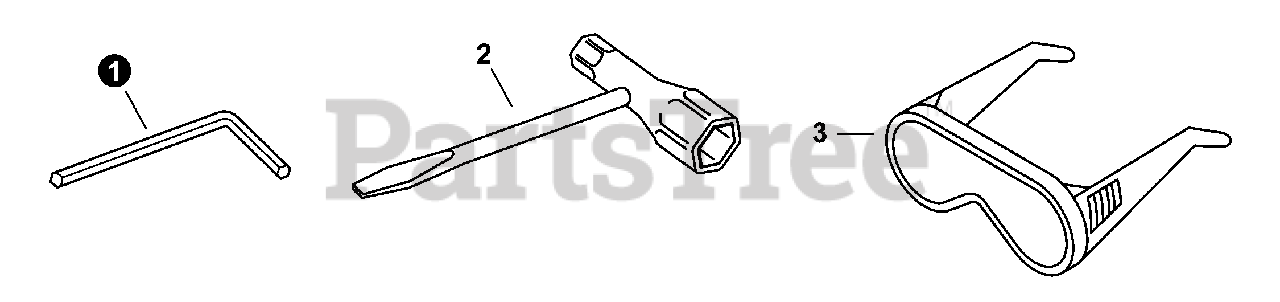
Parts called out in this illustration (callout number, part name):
1	WRENCH, ALLEN 4 MM
2	T-WRENCH 13×19 L= 180
3	GLASSES, SAFETY
